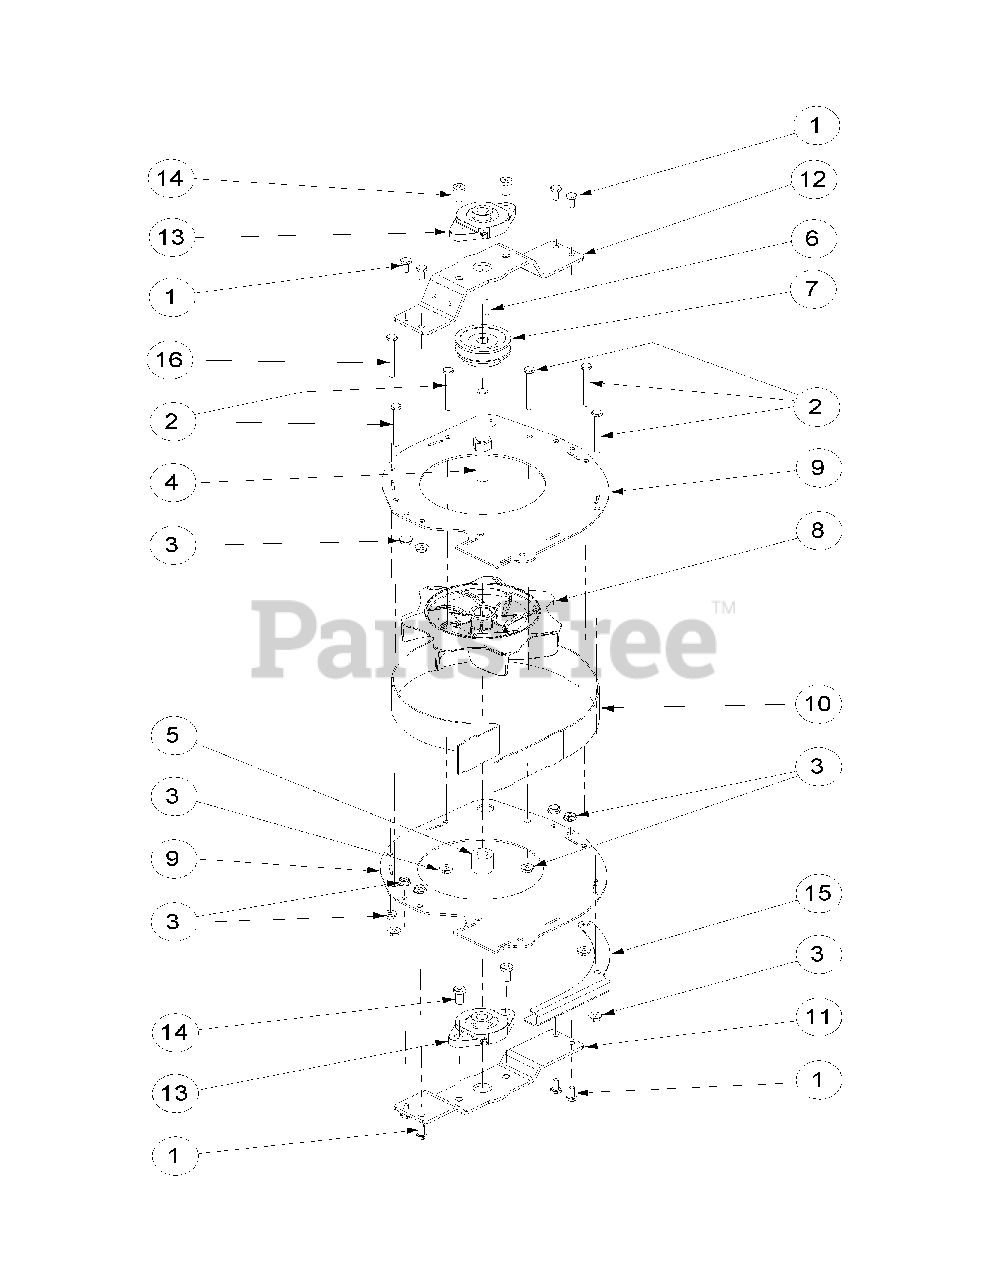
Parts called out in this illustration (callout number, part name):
1	HHCS, 1/4-20 x 0.620
2	HHCS, 1/4-20 x 2.50
3	Hex Nut Flange Lock, 1/4-20
4	Blower Shaft
5	Blower Spacer
6	Key, 1/8 x 1/8 x 1.00
7	Cast Pulley, .500 ID x 2.50 OD
8	Blower Impeller
9	Blower Housing Cover
10	Blower Housing Band
11	Bottom Bearing Mounting Plate
12	Top Bearing Mounting Plate
13	Flange Bearing
14	Socket Head Screw, 3/8-16 x .75
15	Guard Deflector
16	HHCS, 1/4-20 x 2.75
